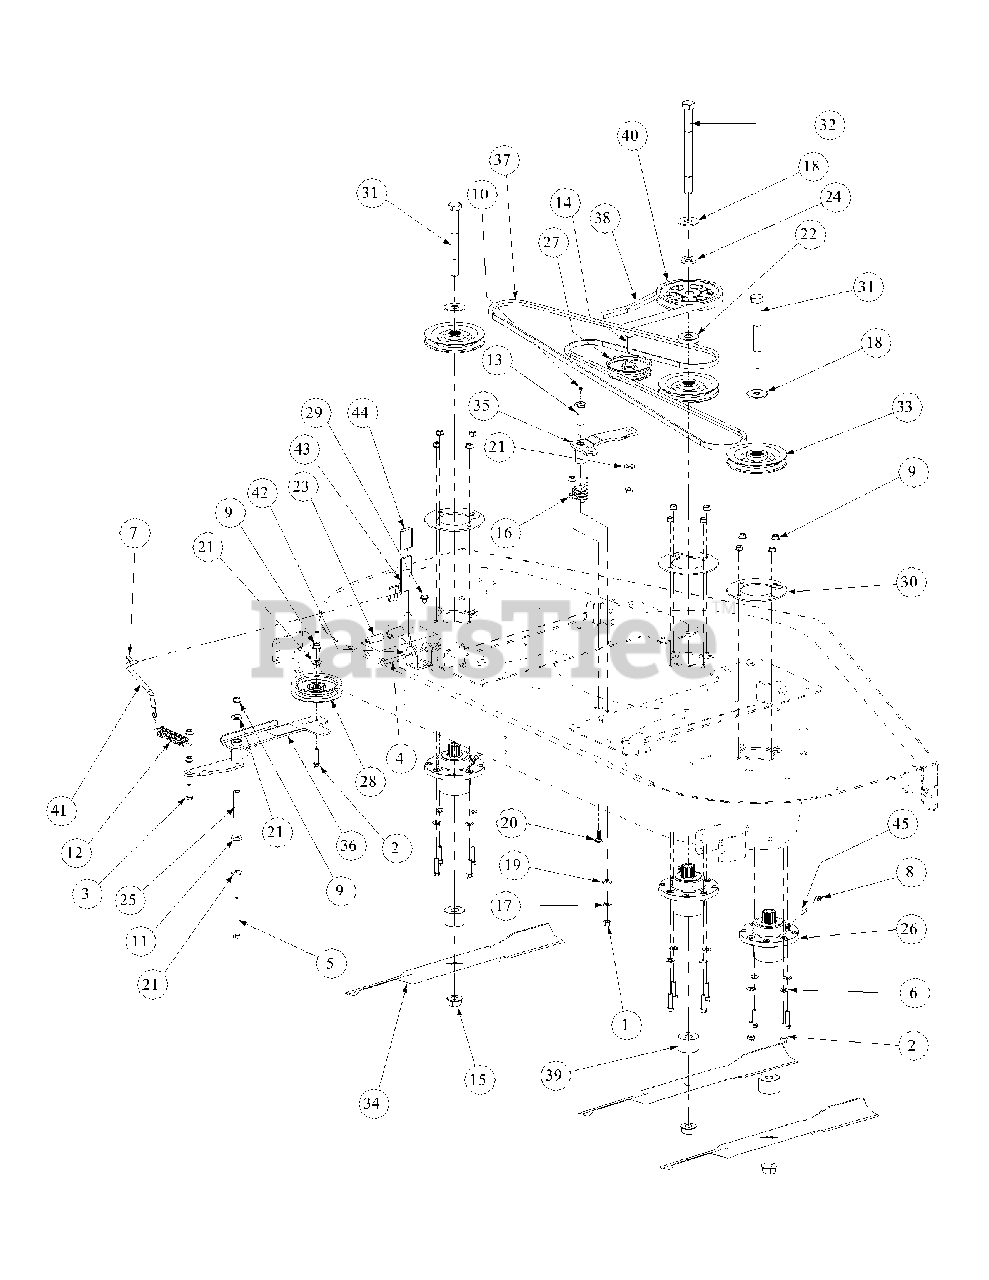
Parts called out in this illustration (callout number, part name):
1	Hex Nut, 7/16-14
2	Hex Cap Screw, 3/8-16 x 1-1/2
3	Hex Cap Screw, 3/8-16 x 1-1/4
4	Hex Cap Screw, 3/8-16 x 2-1/2
5	Hex Cap Screw, 3/8-16, 4.00
6	Flat Washer, 3/8
7	Cotter Pin, 1/16 x 1/2
8	Taper Grease Fitting, 1/4-28, 45 degree
9	Flange Lock Hex Nut, 3/8-16
10	Grease Fitting, 1/4-28 x 3/16
11	Idler Washer
12	Extension Spring, 1.0 x OD x 5.00
13	Shoulder Screw, 7/16-14
14	Hex Carriage Screw, 3/8-16, 1.75
15	Flange Hex Nut, 3/4-16
16	Torsion Idler Spring
17	Lock Washer, 7/16
18	Flat Washer, .781 ID 2.00 OD, .105
19	Flat Washer, .469 ID, .875 OD, .105
20	Carriage Bolt, 3/8-16 x 1
21	Flat Washer, .406 ID, 1.0 OD, .105
22	Spacer, .76 ID x 2.0 OD x .477
23	Spacer, .39 ID x .63 OD x 1.75
24	Spacer .812 ID x .218 LG
25	Spacer, .39 ID x .625 OD x 2.75
26	Aluminum Spindle Assembly
27	Flat Pulley
28	Idler Pulley, 4.06 OD
29	Screw, TT, 3/8-16 x .50,
30	Aluminum Spindle Support Plate
31	Hex Cap Screw, 3/4-16, 7.00
32	Hex Cap Screw, 3/4-16, 9.00
33	V-Pulley, 5.75 OD
34	Bahia Blade, 25.0, .756 ID
35	Idler Arm Assembly, Deck
35	Bearing Sleeve
36	Idler Arm Assembly, Drive
37	V-Belt, B Section x 124.0 LG
38	V-Belt, B Section x 99.25 LG
39	Spacer, .760 ID x 2.00 OD x .330
40	V-Pulley, 6.360 OD x .750 Bore, Cast
41	Spring Tension Rod
42	Tension Idler U-Bracket
43	Handle Tension Weldment
44	Tension Idler Handle Grip
45	Straight Adapter Fitting
